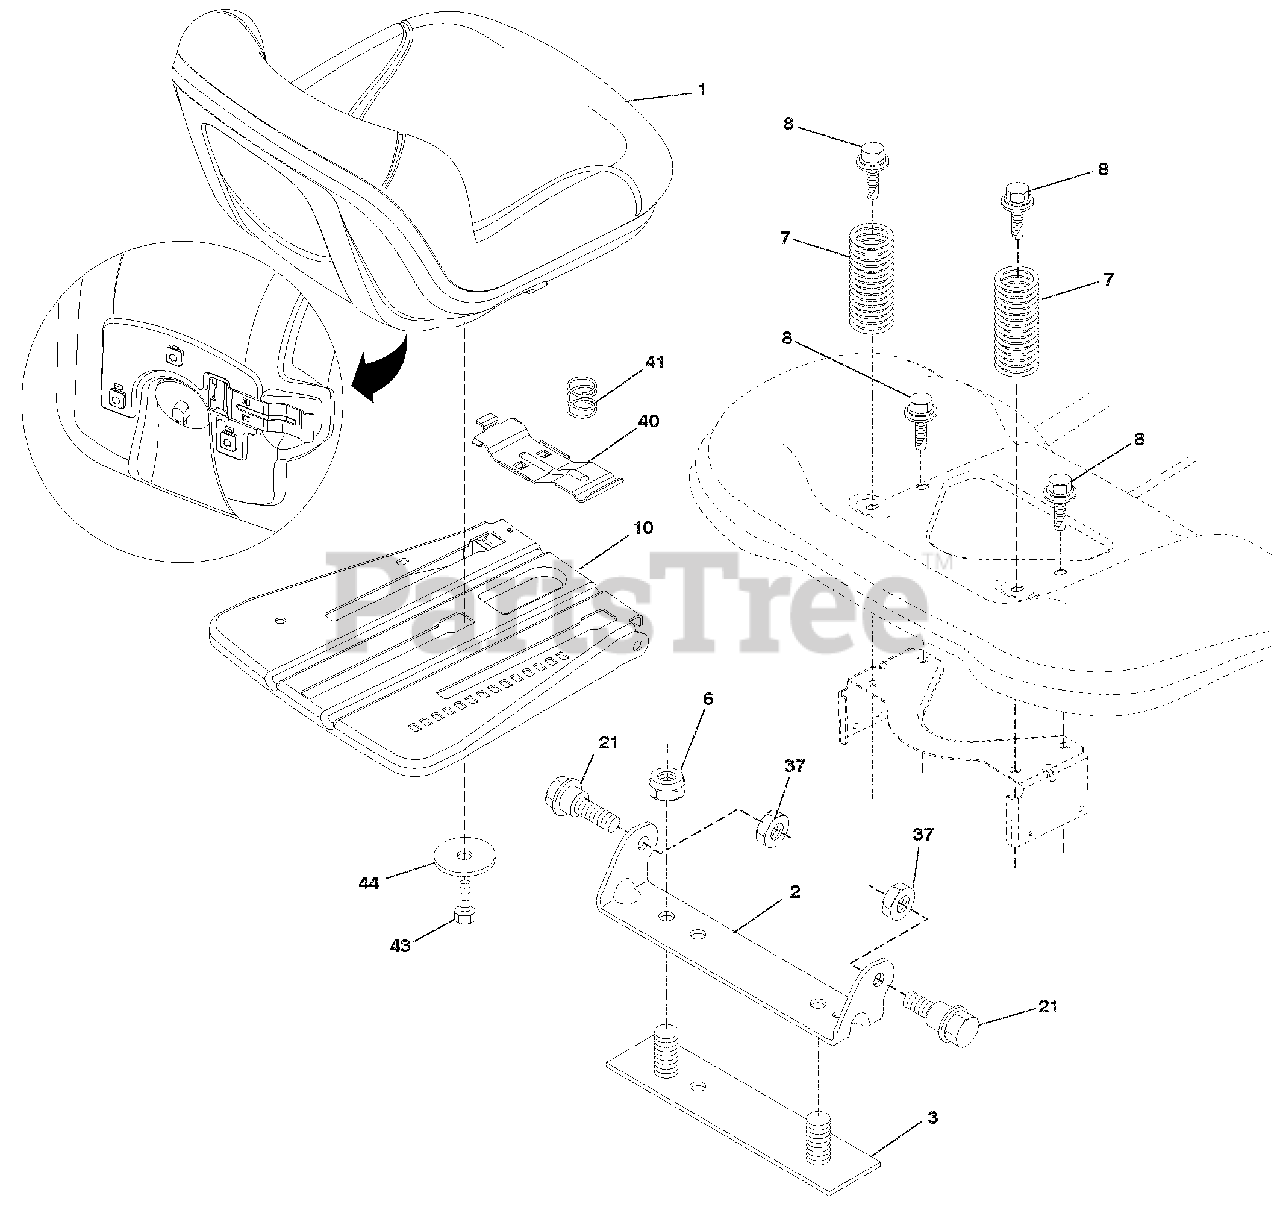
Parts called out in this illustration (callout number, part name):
1	SEAT.TA150.KB/SLD.BLK.ARIENS
2	BRACKET.PIVOT.FENDER.2002
3	STRAP ASM.FENDER.94
6	Locknut, Washer Insert 3/8-16
7	SPRING.SEAT.CPRSN.2.250.BLK.ZI
8	BOLT.5/16-18UNCX3/4 W/SEMS.BLK
10	PAN ASM.SEAT.3PT.
21	BOLT.SHLD.5/16-18 UNC-2A.BLK D
37	Locknut, Washer Insert 5/16-18
40	HANDLE.SLIDE.SEAT.TEX.MILSCO
41	SPRING.LATCH.SEAT.TEX
43	BOLT.FIN.HEX.3/8-16UNC X 3/4
44	WASHER.13/32 X 2 3/8 X 12GA.
